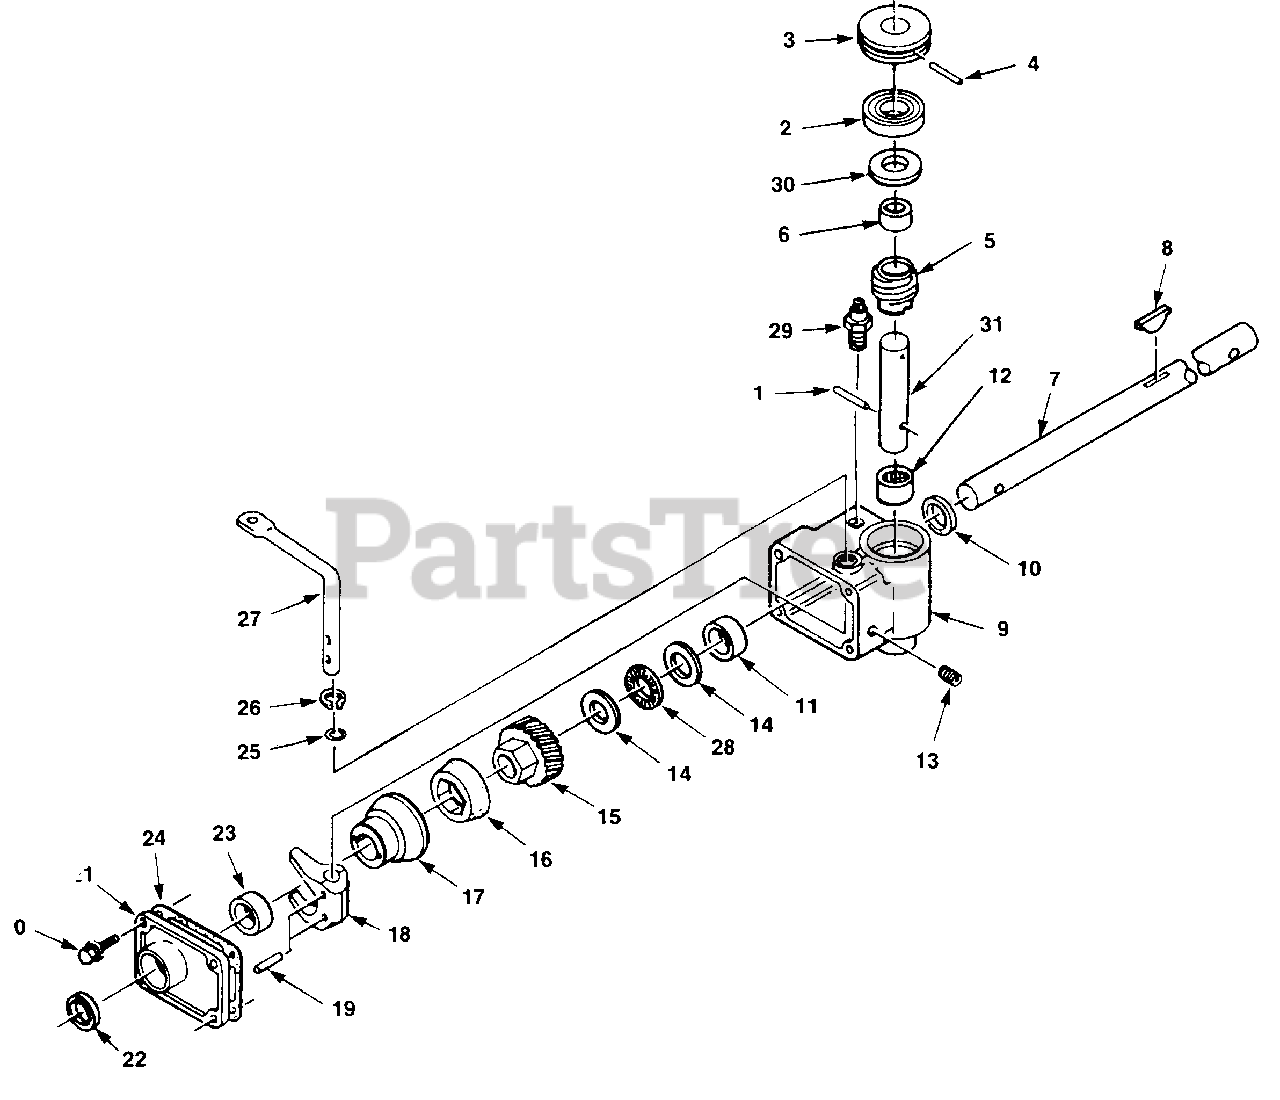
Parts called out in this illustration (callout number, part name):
1	PIN- Roll 3/16 x 7/8"
2	BEARING-Ball
3	PULLEY-Gear box
4	PIN-Roll 3/32 x 1 1/4"
5	WORM & SPACER
6	SPACER-Worm
7	SHAFT-Drive
9	HOUSING-Gearbox
11	BUSHING-Sleeve
12	BEARING-Needle
13	PLUG-Pipe
14	RACE-Thrust
15	GEAR-Helical
16	CONE-Friction
17	DRUM-Clutch
18	FORK-Shift
19	PIN-Groove
20	SCREW-(1/4-20 x 7/8")
21	GEAR BOX COVER ASSEMBLY
23	BUSHING-Sleeve
24	GASKET-Gearbox
26	TRU-ARC RING
27	LEVER-Shift
28	BEARING-Needle
31	WORM-Shaft
